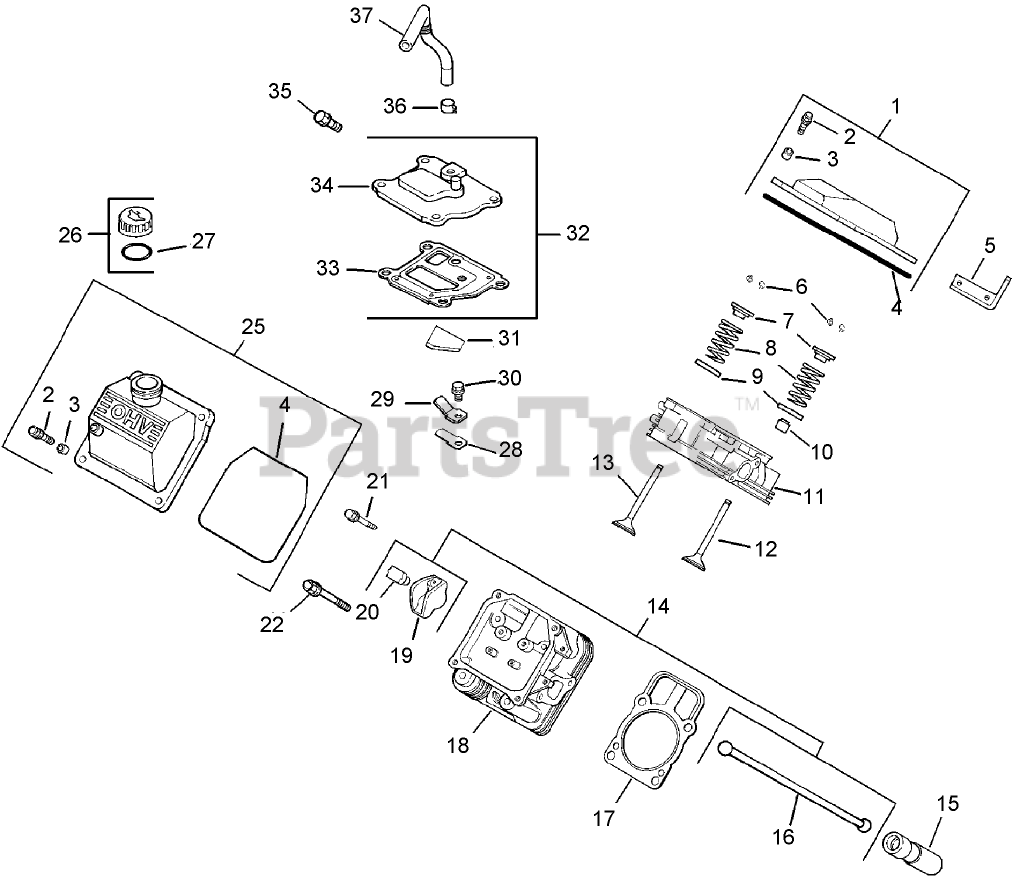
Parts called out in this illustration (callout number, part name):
1	Kit, valve cover-plain (Includes 2-4)
2	SCREW-FLANGE (M6X1.0X30)
3	Spacer
4	O-Ring
5	STRAP-LIFTING
6	RETAINER KIT
7	CAP-SPRING, VALVE
8	SPRING-VALVE
9	RETAINER-SPRING
10	SEAL-STEM, VALVE
11	No. 1 Cylinder Head ASM
12	VALVE-INTAKE (STD)
13	VALVE-EXHAUST (STD)
14	Kit, valve train (Includes 16, 19, 20)
15	Lifter-Valve
16	ROD-PUSH
17	Gasket-Cylinder Head
18	No. 2 Cylinder Head ASM
19	ARM-ROCKER
20	Pivot-Arm, Rocker
21	SCREW-FLANGE (M6X1.0X34)
22	STUD (M8X1.25xM10X1.5x105MM)
25	Kit, valve cover-oil fill (Includes 2-4)
26	Kit, oil fill cap (Includes 27)
27	O-RING
28	REED-BREATHER
29	Retainer-Reed, Breather
30	SCREW-HHFTF (M5X.80X10)
31	Filter-Breather
32	Kit, breather (Includes 32-34)
33	Gasket-Breather
34	COVER-BREATHER
35	SCREW-HHFTF (M6X1.0X20)
36	Clamp-Hose
37	Hose-Breather
